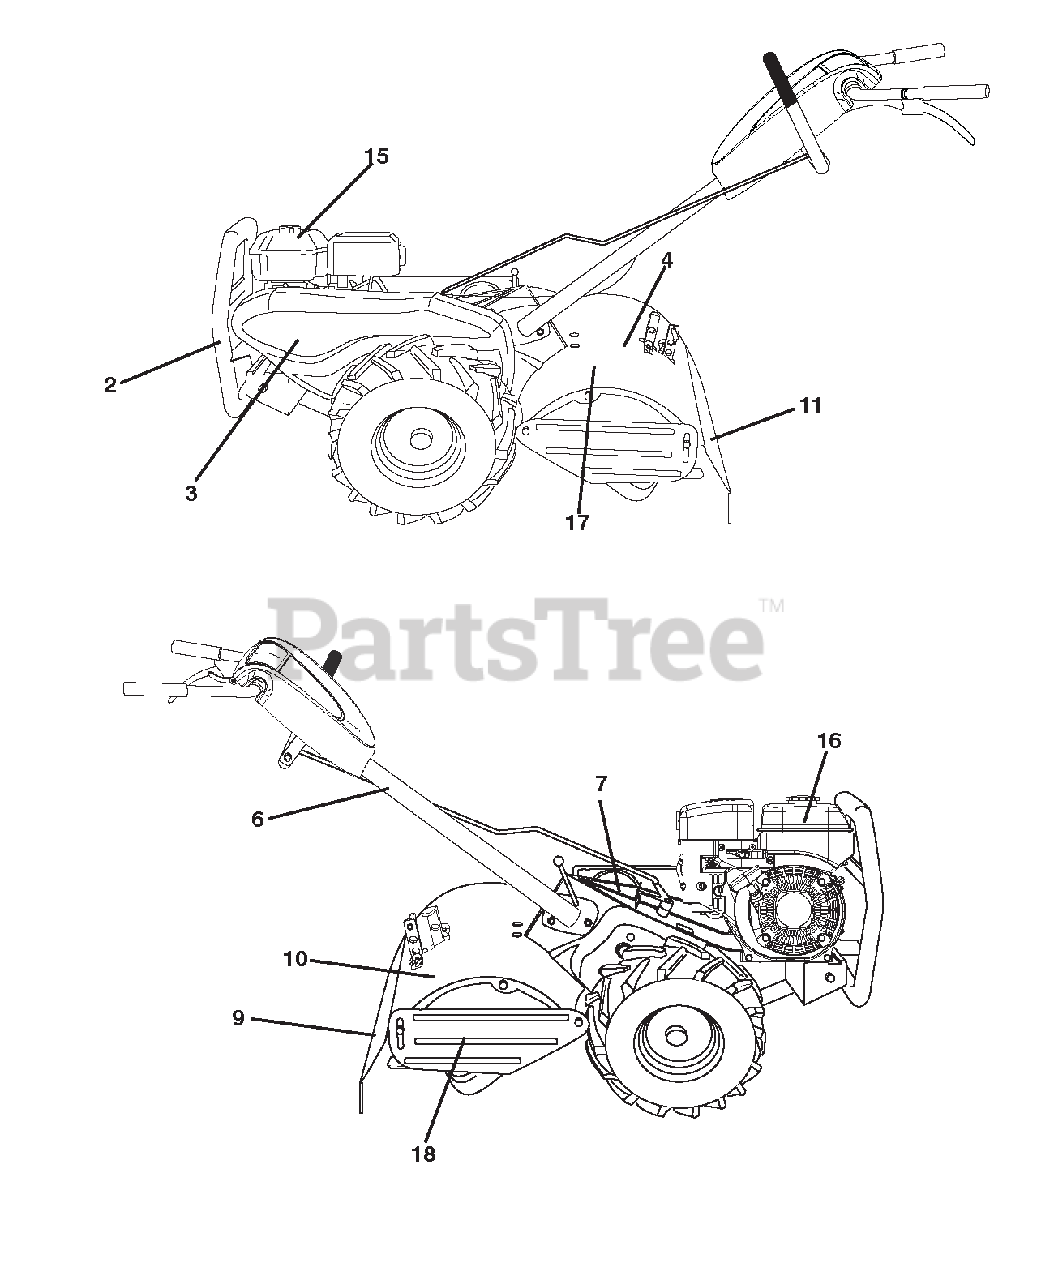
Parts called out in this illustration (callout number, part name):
2	DECAL, SUBARU TINE SHIELD
3	DECAL, BELT GUARD
4	DECAL, TINE SHIELD FORWARD
6	Decal, Hand Placement
7	Decal, Shift Indicator
9	Decal, Warning, DRT
10	DECAL, TINE SHIELD DRT REV
11	DECAL, TINE SHIELD GEAR
15	DECAL, ETHANOL
16	Decal, Spark Arrester
17	DECAL, TINE
18	DECAL, SIDE
